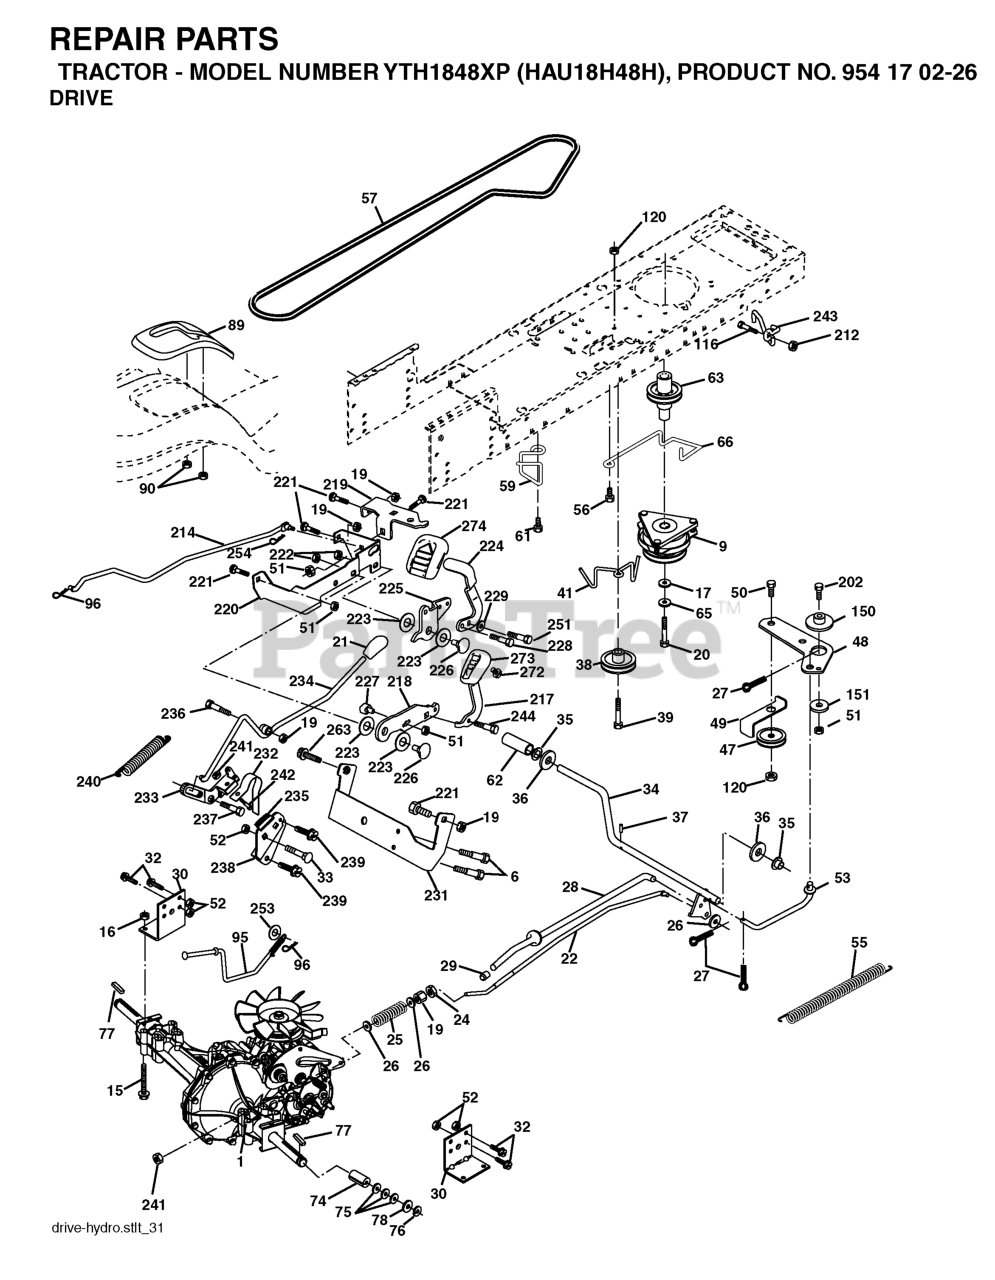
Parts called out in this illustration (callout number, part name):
6	SCREW 5/16"
9	CLUTCH ELECTRIC
15	BOLT HEX 5/16-18 GR 5
16	NUT.71038.31-18.HEX.NYLOCK
19	NUT
20	BOLT HEX 7/16-20X4-1/4"
22	ROD.BRAKE.HG-0510.PEDAL.CONTRL
24	NUT
25	SPRING ROD LT
26	WASHER
27	COTTER PIN
28	ROD, PARKING BRAKE
29	PLUNGER CAP
30	BRKT, TRNSXLE MNT 20"
32	BOLT
33	RP BOLT 5/16-18 X3/4 ZN/YEL GR
34	SHAFT, FOOT PEDAL
35	BEARING.NYLON
37	DRIVE PIN
38	PULLEY IDLER COMPOSITE
41	KEEPER, BELT IDLER
47	IDLER PULLEY
48	BELLCRANK, CLUTCH
49	RETAIN BELT
50	BOLT.3/8-16X1.50
52	LOCKNUT
53	LINK, CLUTCH LT
55	SPRING, RETURN LT
56	SCREW.3/8-16
57	DRIVE BELT, LTH & YTH TRACTORS
59	KEEPER, BELT CENTER
61	SCREW 3/8-16X.875
62	PEDAL COVER T
63	PULLEY- ENGINE
65	LOCKWASHER
66	KEEPER BELT ENGINE
74	SPACER AXLE
77	SQUARE KEY
89	PAD.FOOTREST
90	NUT.PUSH.3/16
95	ROD BYPASS
96	RETAINER M
116	BOLT D
120	NUT LOCK FLG 3/8-16 UNC
150	SPACER, RETAINER
151	WASHER 12/32X2X10GA
212	NUT
214	LINK TRANSAXLE
217	PEDAL REVERSE
218	ARM CONTROL PEDAL REVERSE
219	BRACKET FREST PDL
220	BRACKET MTG.PDL CONTROL
221	Bolt - Rd. Hd. Sq. Neckiage 3/8 16 x 3/4
222	Nut, Crownlock Hex 7/16-14 unc
223	WASHER NYLON
224	PEDAL FORWARD
225	ARM CONTROL PEDAL FORWARD
226	BOLT PIVOT SPACER
227	CAM REVERSE PEDAL LT
228	BOLT SHOULDER
229	WASHER.SERRATED.5/16X.75
231	STRAP TORQUE
232	ACUATOR CRUISE DISENGAGE
233	PAWL CONTROL CRUISE
234	LEVER CONTROL CRUISE
235	SECTOR CONTROL CRUISE
237	SHOULDER BOLT 5/16-18TT
238	ARM MTG.CRUISE SECTOR
239	Screw 5/16-18 x 1/2 Hex, Self Tapping 5/16-18 x 1/2
240	SPRING RETURN CRUISE CONTROL
241	NUT CENTERLOCK
242	BOLT
243	BRKT ASM MTNG
244	CAPSCREW.HXHD.FLG.5/16-18X.625
251	SCREW 5/16-18X1
254	CLIP RETAINER
271	SCREW, 3/8-16X3/4
272	SCREW, 5/16-18 X 1/2
274	COVER PEDAL FORWARD
